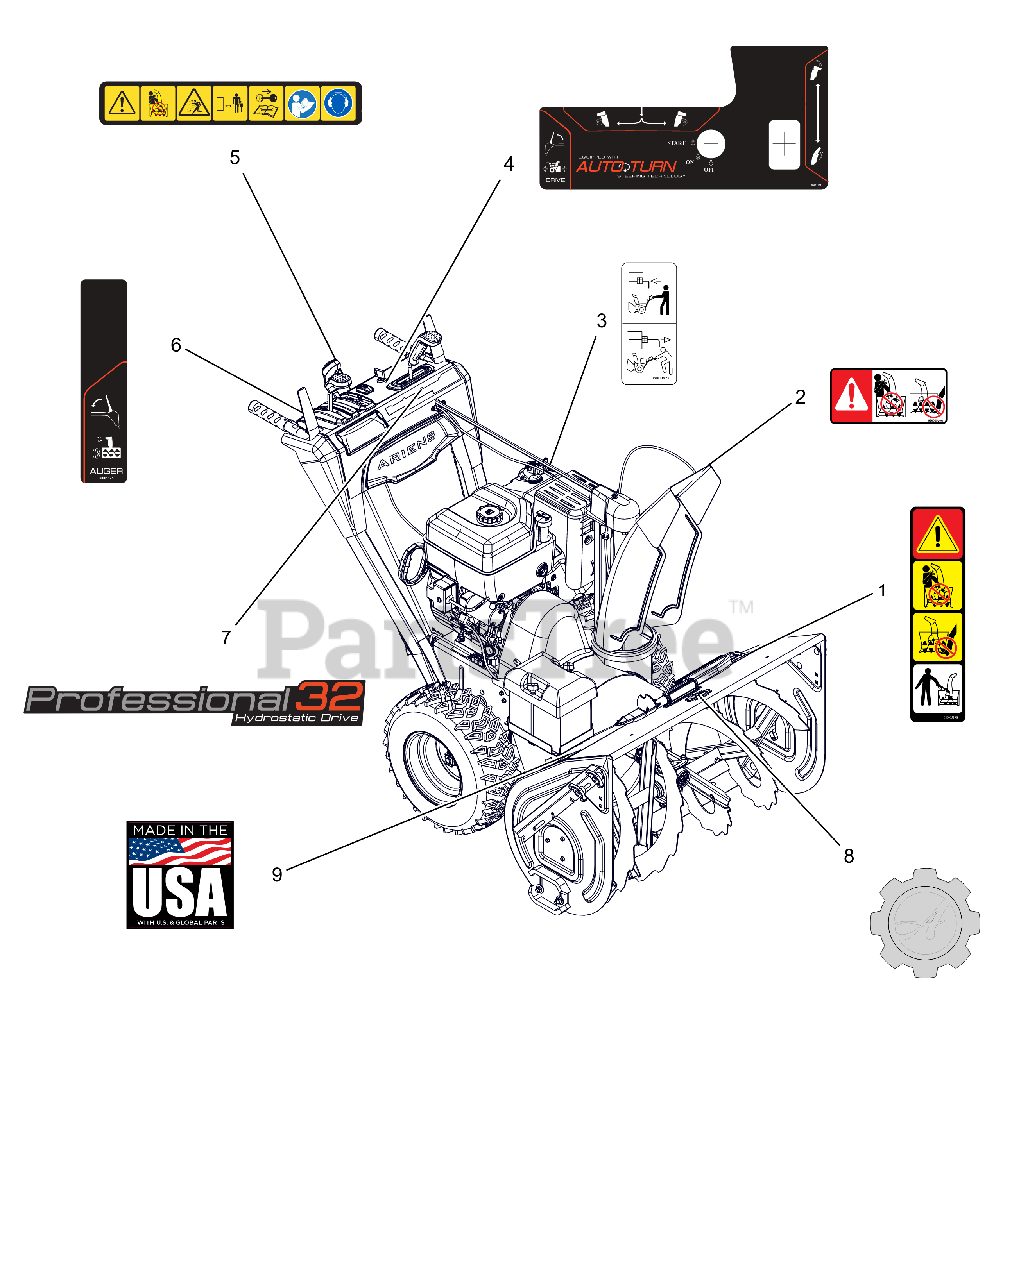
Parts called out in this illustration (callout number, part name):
1	DECAL, DANGER - ROTATING PARTS
2	DECAL, DANGER
3	DECAL, BYPASS
4	DECAL,CONTROL-LG QT2 12V
5	DECAL,DASH - SAFETY
6	DECAL,CONTROL-RH CONTROL
7	DECAL, DASH - PRO HYDRO 32
8	DECAL, ARIENS-GEAR BADGE -THK
9	DECAL, MADE IN USA
